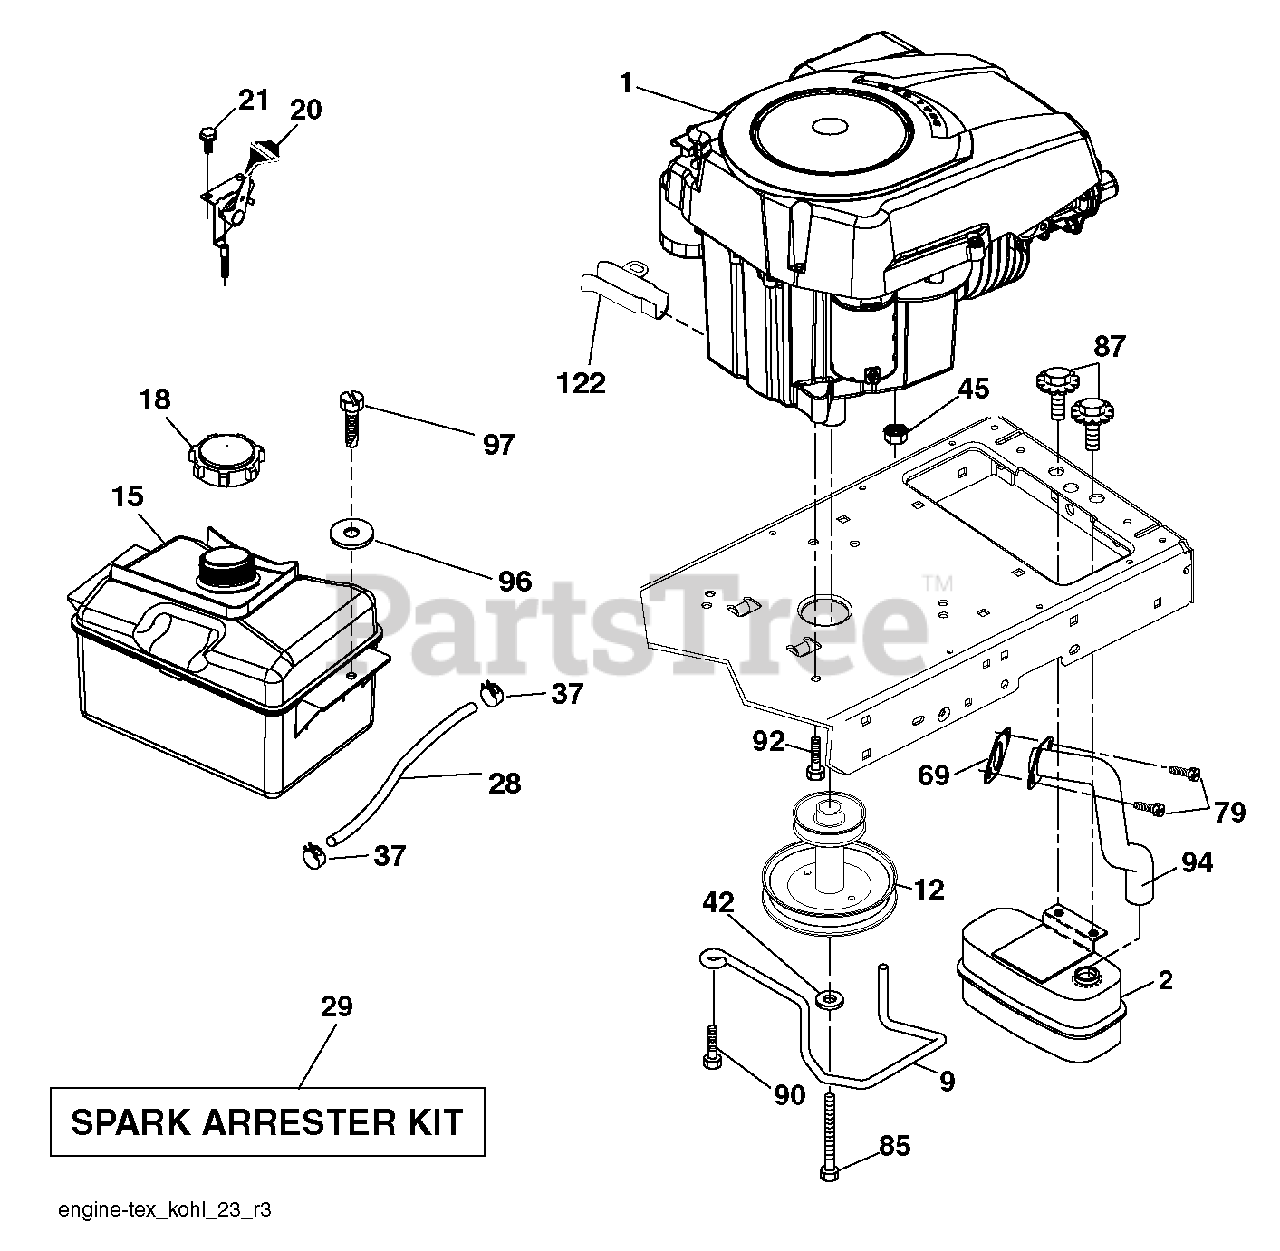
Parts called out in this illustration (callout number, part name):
9	KEEPER.BELT.ENGINE.4.2
21	SCREW.#10 X 0.750.BOS THREAD
29	ARRESTER SPARK (OPTIONAL)
37	HOSE CLAMP
42	LOCKWASHER
79	SCREW.SOCKET HD.5/16-1
87	BOLT, 5/16-18 X 1 3/4
90	SCREW 3/8-16X1
92	SCREW 3/8-16X1
97	SCREW HEXWSHR 1/4-20X3/4
